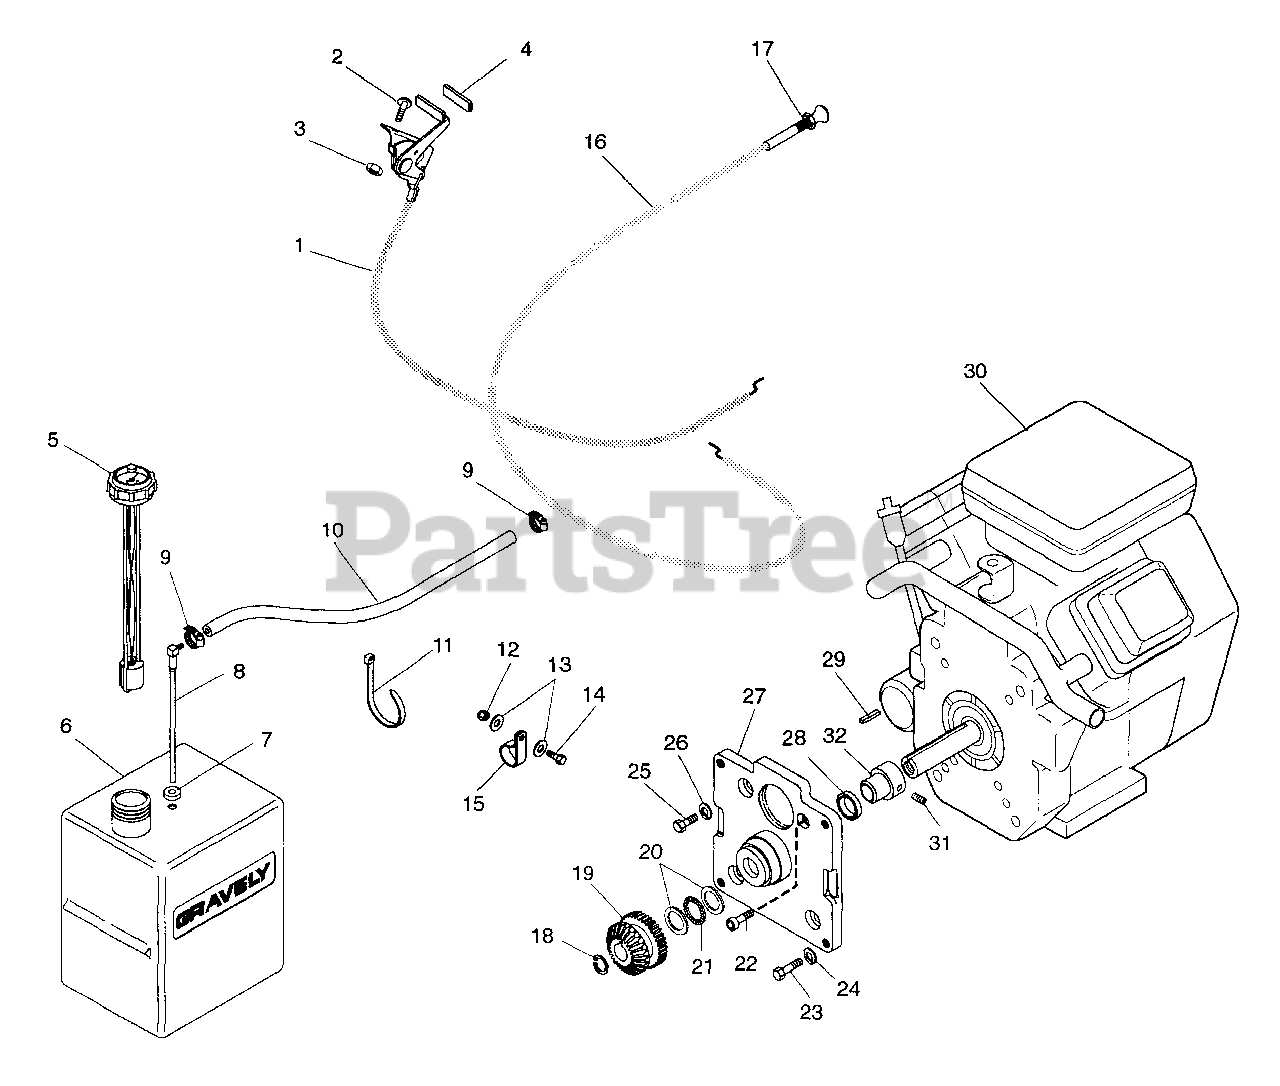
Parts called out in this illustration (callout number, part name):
1	Throttle Cable
2	Screw-Machine 10-32 x .50
3	Nut-Locking 10-32 Nylon
4	Knob
5	Gauge, Fuel
6	Tank, Fuel
7	Bushing
8	Fitting, Tank
9	Clamp-Hose
10	Gas Line Bulk
11	Tie, Cable
12	Nut-Locking-Nylon .312-18 Grade 2
13	Washer-Flat-Steel .344 x .688 x .065
14	Bolt-Hex .31-18 x 1.00 Grade 5
15	Cable Clamp
16	Control, Choke
17	Nut-Jam .315-24
18	Ring-Retaining-Internal 1.111 x .042
19	Input Gear
20	Washer-Thrust
21	Bearing-N-Thrust 1.0 x 1.55 x .078
22	Screw-Socket Head .44-14 x 1.00
23	Bolt-Hex .50-13 x 1.25 Grade 5
24	Washer-Lock .50
25	Bolt-Hex .44-14 x 1.125
26	Washer-Lock .438 x .133
27	Adapter, Engine
28	Seal 1.25 x 1.628 x .250
29	Key-Square .248 x 1.25 x .248
30	Engine, 16 HP B&S Vanguard
31	Screw-Set .25-20 x .38
32	Spacer
